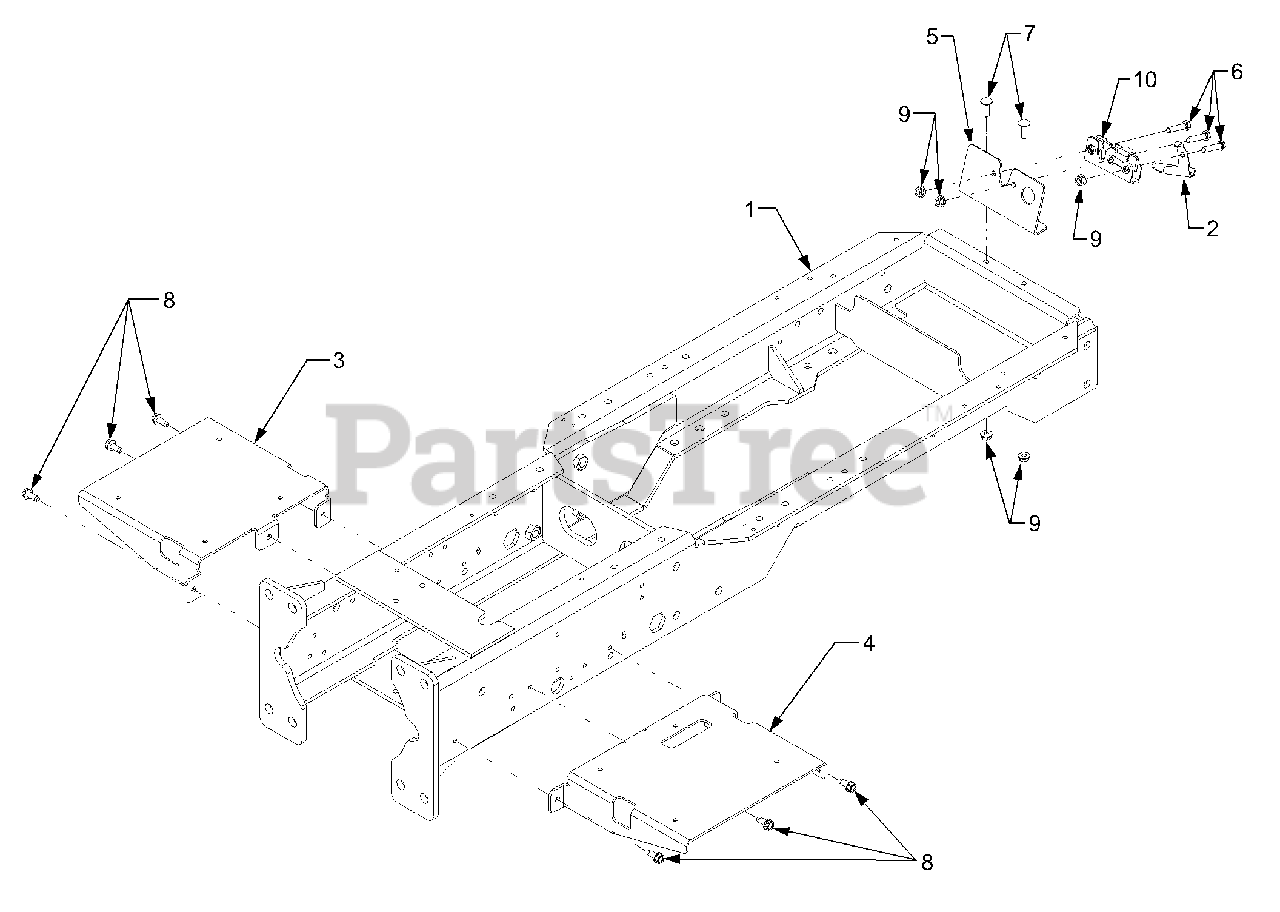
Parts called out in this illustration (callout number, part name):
2	Lever, Hood Latch
3	Bracket, Running Board Mtg. LH
4	Bracket, Running Board Mtg. RH
5	Bracket, Hood Latch Mtg.
6	Screw, Hex Cap, 5/16-18 x 1.375 GR5
7	Screw, Carriage, 5/16-18 x 1.0
8	Screw, Hex Wash. Hd. 5/16-18 x .75
9	Nut, Hex Flange Lock, 5/16-18
10	Latch, Hood
